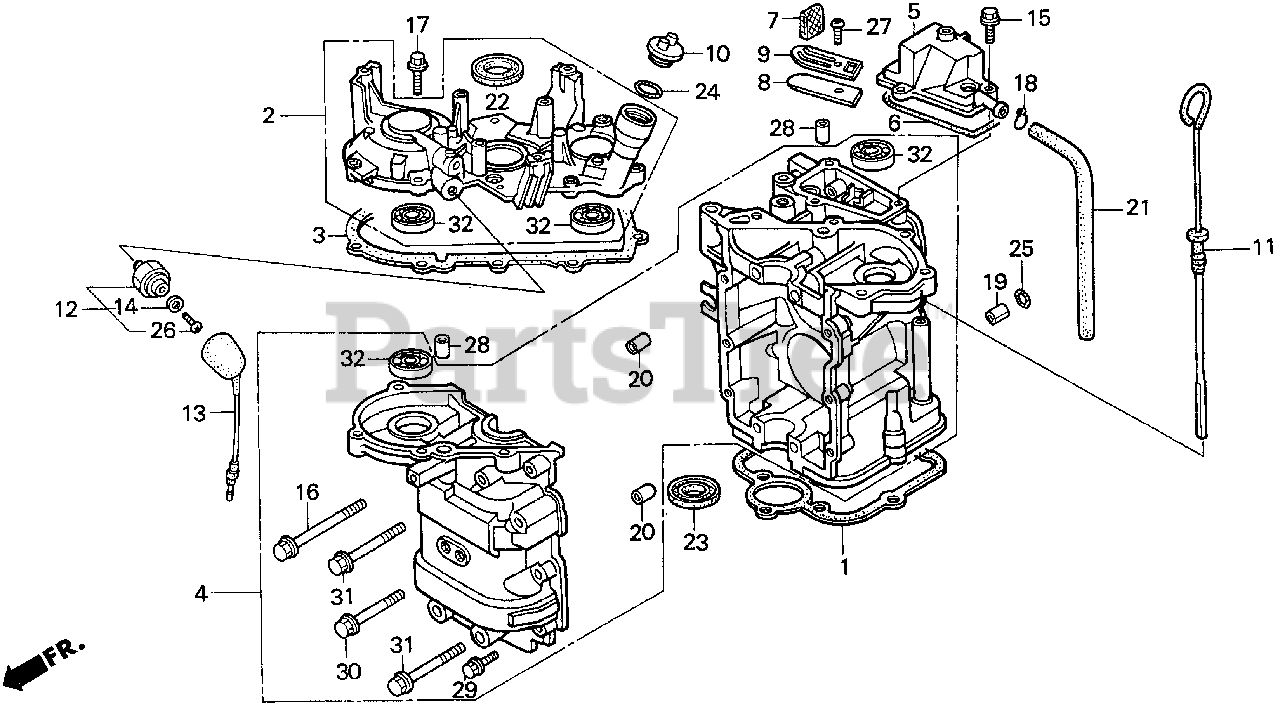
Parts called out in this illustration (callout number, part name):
1	GASKET, OIL PAN
2	CASE ASSY., STARTER *NH8* (DARK GRAY)
3	GASKET, STARTER CASE
4	CYLINDER ASSY. *NH8* (DARK GRAY)
5	COVER, BREATHER *NH8* (DARK GRAY)
6	GASKET, BREATHER COVER
7	FILTER, BREATHER
8	PLATE, VALVE
9	STOPPER, VALVE
11	DIPSTICK, OIL
12	SWITCH, OIL PRESSURE
13	WIRE, OIL PRESSURE SWITCH
14	WASHER (4MM)
15	BOLT, FLANGE (6X20)
16	BOLT, FLANGE (8X75)
17	BOLT, FLANGE (6X25)
18	CLIP, TUBE (B12.5)
19	PIN, SPECIAL (6.5X10)
20	PIN, DOWEL (10X12)
21	TUBE, BREATHER
22	OIL SEAL (32X44X7)
23	OIL SEAL (30X42X7)
24	O-RING (26X2.7)
25	O-RING (6.8X1.9)
26	SCREW, PAN (4X6)
27	SCREW, PAN (5X10)
28	PIN A, DOWEL (8X12)
29	BOLT, FLANGE (6X25)
30	BOLT, FLANGE (6X50)
31	BOLT, FLANGE (8X65)
32	BEARING, RADIAL BALL (6001)
